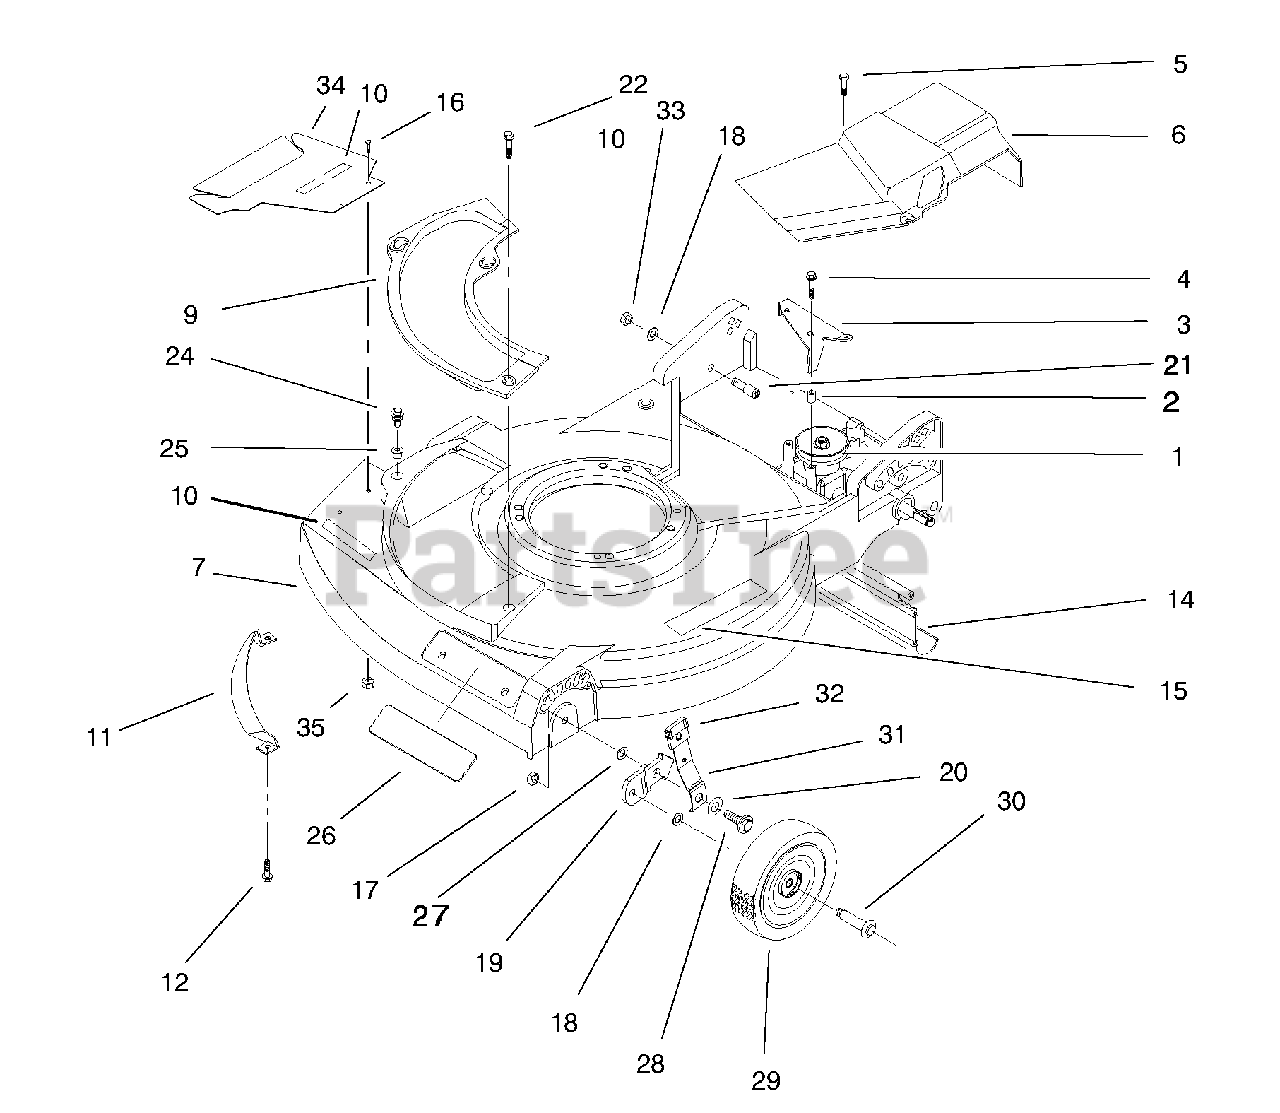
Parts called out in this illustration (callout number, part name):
1	Gear Case Assembly
2	Bushing-Spacer
3	Bracket-Actuator
4	Screw
5	Screw-Thr'd Form
6	Cover-Drive
7	Housing (Incl. Ref. #10, & 15)
9	Plate-Cover
10	Decal-Danger
11	Toe Bar
12	Screw-Hex Washer Hd.
14	Shield-Trailing
15	Decal-Warning
16	Screw-Hex Hd. Cap
17	Nut-Lock
19	Bracket-Wheel Height Adj.
20	Washer-Belleville
21	Bolt-Shoulder
22	Screw-Hex Hd. Cap
24	Screw-Sems Thr'd Form
28	Bolt-Shoulder
29	Wheel & Tire Assembly-6"
30	Bolt-Wheel
31	Spring Arm Ass'y-Front
32	Knob-Height Adjust
33	Nut-Lock
34	Guard-Plate
35	Nut-Lock
